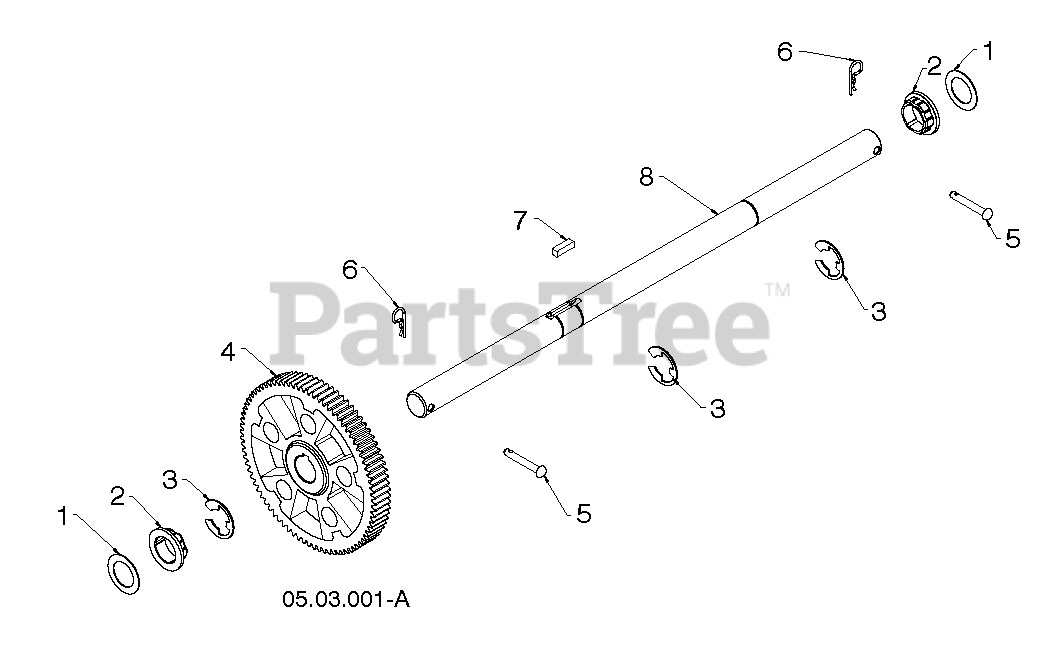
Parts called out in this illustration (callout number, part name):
1	WASHER 1.00
2	BUSHING,HEX BUSHING (1
3	E RING HYT
4	GEAR 80T DRIVEN_2PC
5	RIVET
6	RETAINER M
7	KEY, SQUARE 1/4 X .875
8	SHAFT SHAFT,AXLE,
